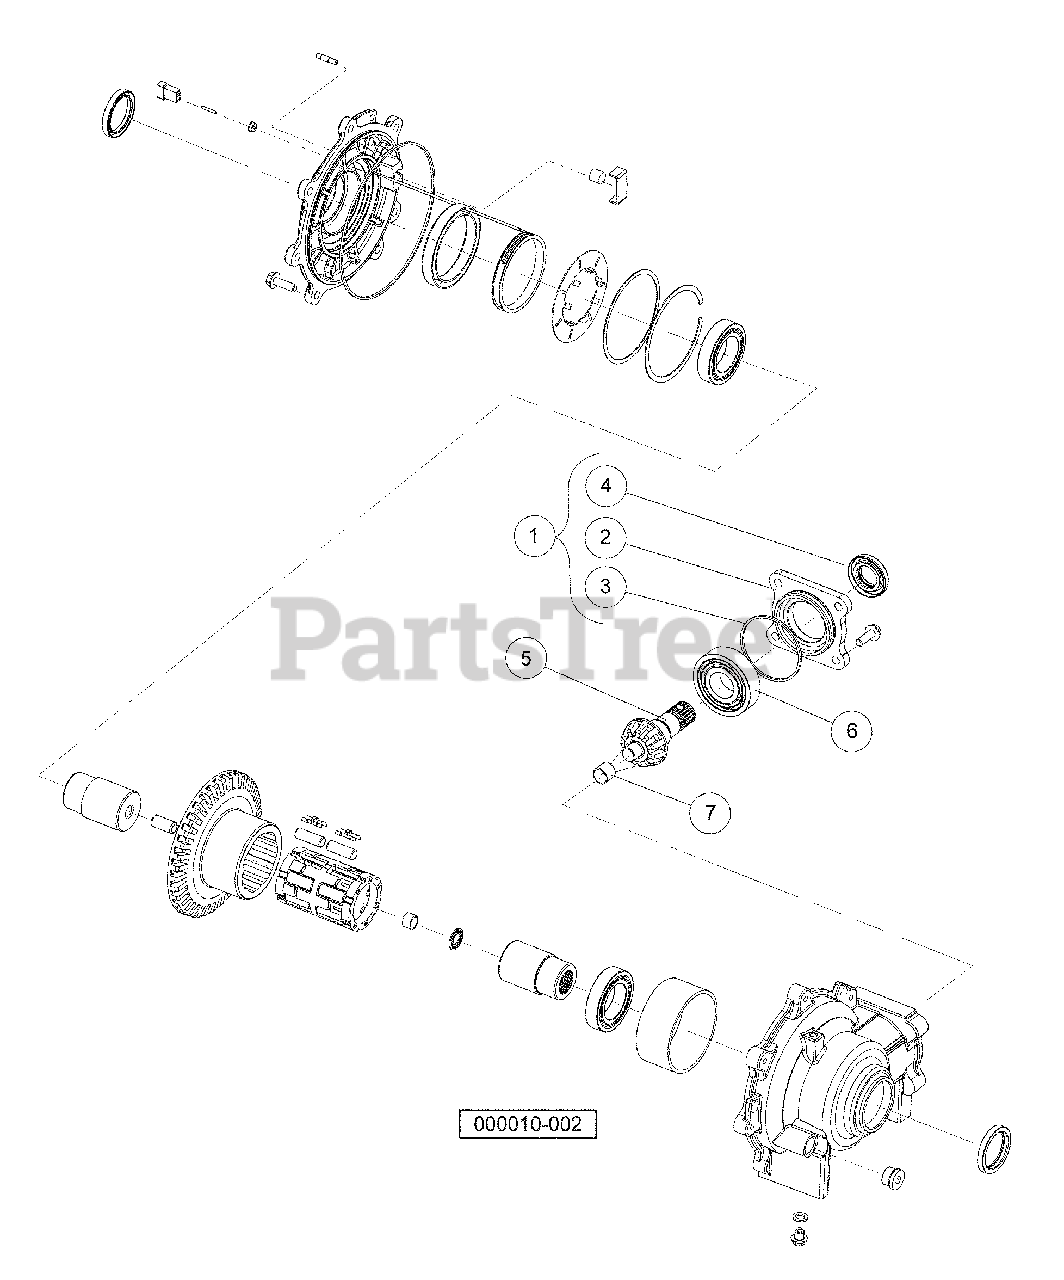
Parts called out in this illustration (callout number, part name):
1	Kit, Assy, Input Cover Plate
2	Cover, Input, Machined
3	O-Ring
4	Oil Seal, Triple-Lipped
5	Shaft, Pinion, Machined
6	Bearing, Ball
7	Bushing, Plain 16 Id X 15 Wide
